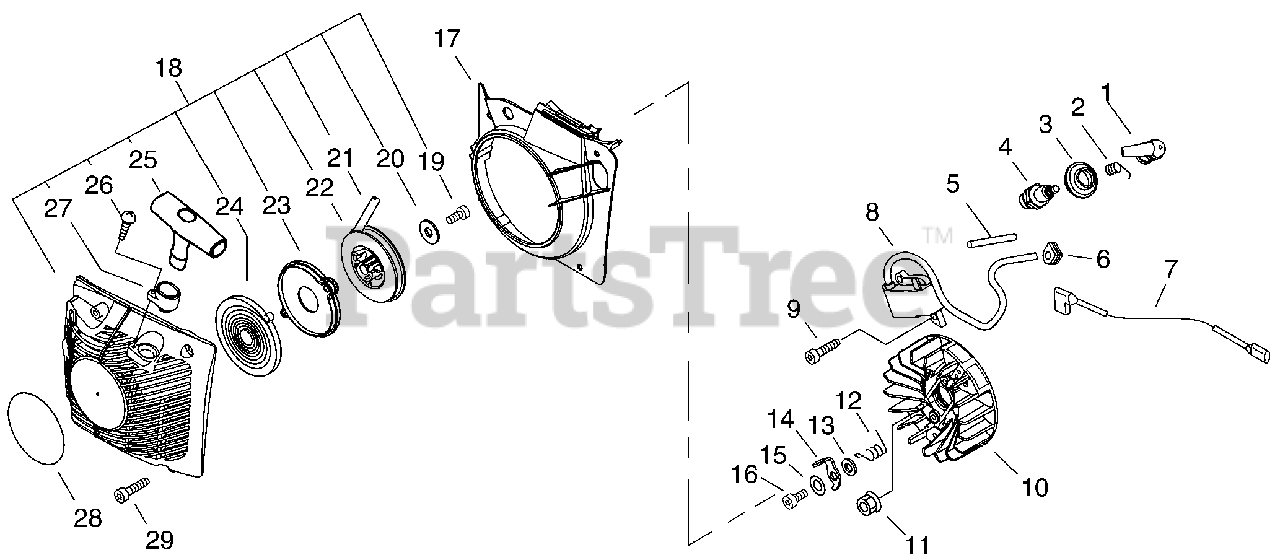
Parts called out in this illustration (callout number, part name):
1	CAP, SPARK PLUG
2	TERMINAL, SPARK PLUG
3	SEAL, SPARK PLUG
4	SPARK PLUG - BPM8Y
5	TUBE, IGNITION COIL 6×7.2×70
6	GROMMET
7	LEAD L= 280
8	COIL, IGNITION
9	BOLT, TORX 5×16
10	FLYWHEEL
11	NUT, FLANGE M8
12	SPRING, TORSION
13	SPACER 5.2×8×2.1
14	PAWL, STARTER
15	WASHER 5.5×12×0.8
16	BOLT, TORX 5×16
17	COVER, FAN
18	STARTER ASSY, RECOIL
19	BOLT, TORX 5×10
20	WASHER 5.2×16×1.0
21	ROPE, STARTER 4.0×950
22	REEL, ROPE
23	PLATE, STARTER
24	SPRING, RECOIL
25	GRIP, STARTER
26	SCREW, TAPPING 3×16
27	GUIDE, ROPE
28	LABEL, STARTER - ECHO
29	BOLT, TORX 5×16
